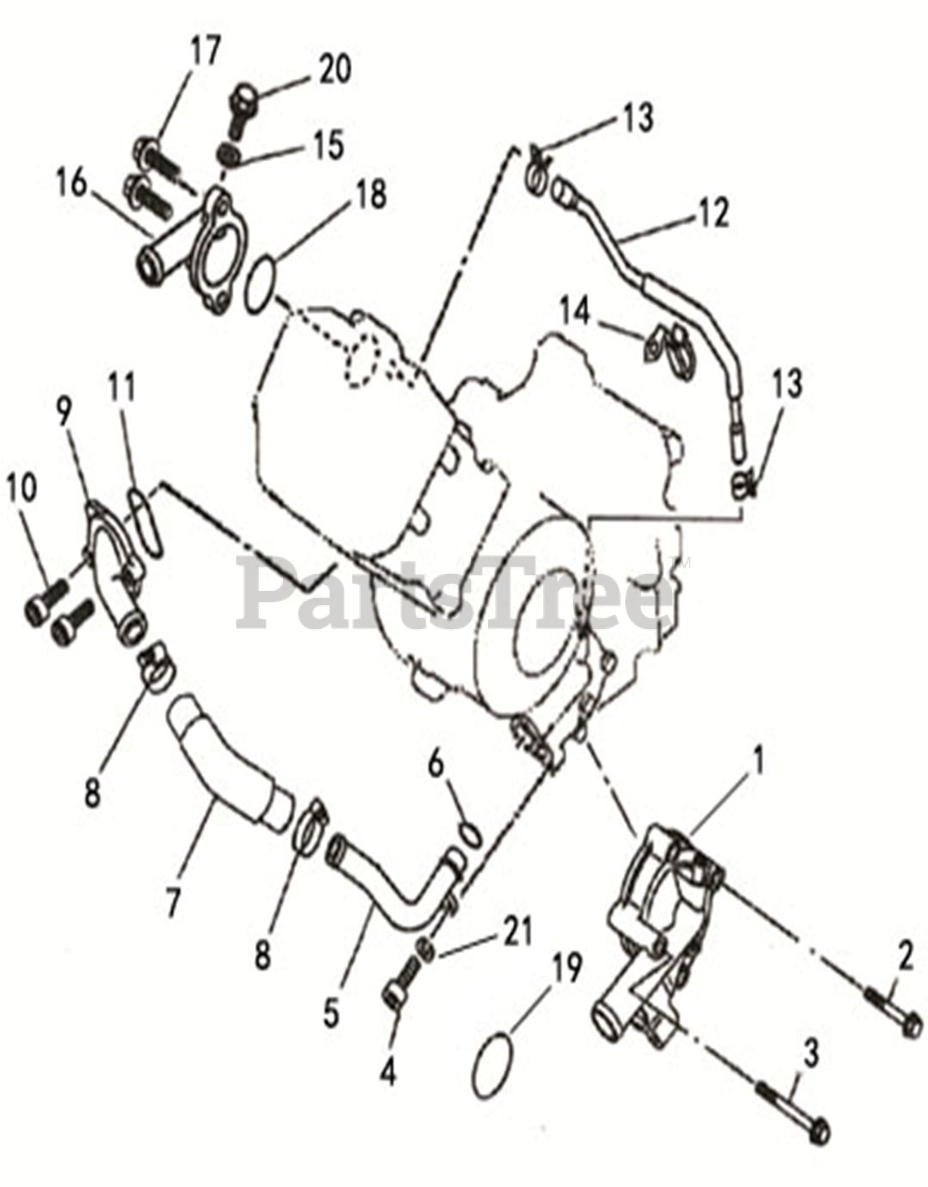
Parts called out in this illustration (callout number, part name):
1	WATER PUMP ASSEMBLY
2	HEX FLANGE BOLT M6X45
3	HEX FLANGE BOLT M6X65
4	HEX FLANGE BOLTS M6X16
5	WATER PIPE (CHALLENGER 750)
6	O-RING 20.7X2.6
7	HOSE (CHALLENGER 750)
8	HOSE CLAMP ASSEMBLY
9	OUTLET WATER HOSE
10	HEX FLANGE BOLTS M6X20
11	O-RING 33.4X2.4
12	WATER PIPE I
14	PIPE CLAMP
15	ALUMINUM WASHER 6X12X1.5
16	THERMOSTAT COVER
17	HEX FLANGE BOLTS M6X20
18	THERMOSTAT COVER SEAL
19	O-RING 34.2X2.5
20	HEX FLANGE BOLT M6X12
21	SPRING WASHER
